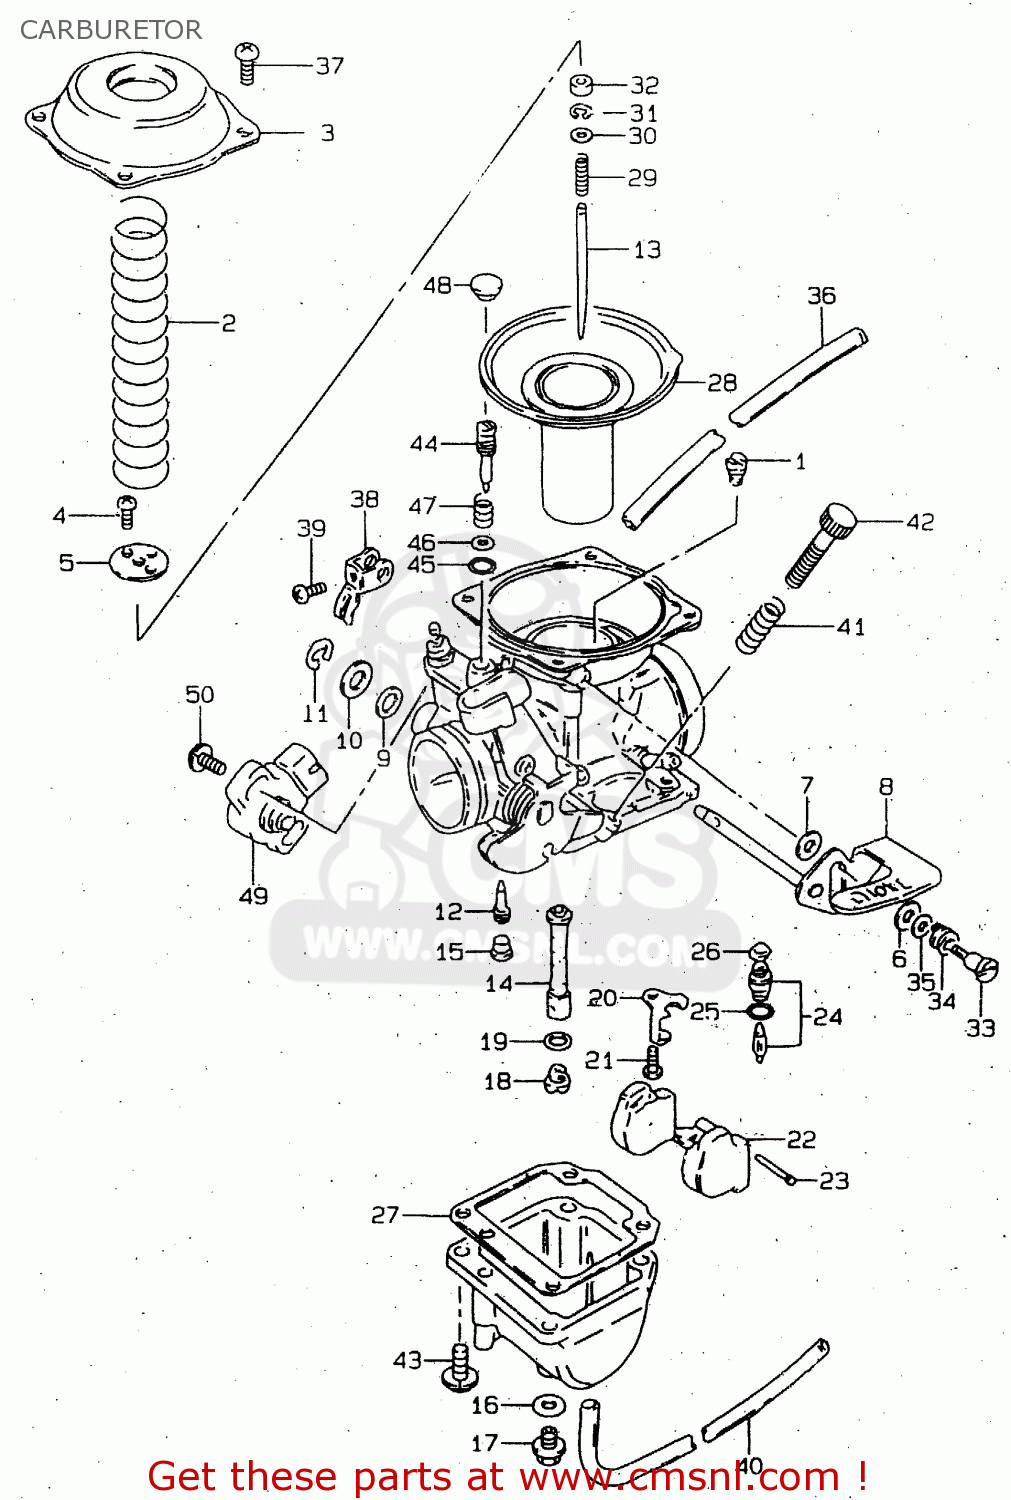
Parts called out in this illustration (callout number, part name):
1	JET,MAIN(180)
2	SPRING
3	COVER
4	SCREW
5	PLATE
6	PACKING (NAS)
7	WASHER(4.1X12X0.8)
8	SHAFT ASSY,STARTER
9	SEAL
10	GASKET,THROTTLE SHAFT (NAS)
11	E RING
12	JET,PILOT(35)
13	NEEDLE,JET
14	JET,NEEDLE(P-2)
15	PLUG,NEEDLE JET
16	GASKET (NAS)
17	PLUG,DRAIN
18	JET,MAIN(97.5)
19	WASHER
20	PLATE
21	SCREW 4X6
22	FLOAT
23	PIN,FLOAT
24	VALVE ASSY,NEEDLE
25	O-RING,NEEDLE VALVE
26	FILTER
27	GASKET,FLOAT CHAMBER (NAS)
28	DIAPHRAGM ASSY
29	SPRING
30	WASHER
31	CLIP
32	RING
33	SCREW
34	SPRING
35	WASHER,STARTER SHAFT
36	HOSE(5X8.2X600)
37	SCREW
38	LEVER
39	SCREW
40	HOSE(3.5X6.5X600)
41	SPRING,THROTTLE SCREW
42	ADJUSTER
43	SCREW
44	SCREW,PILOT
45	O RING,PILOT AIR SCREW
46	WASHER
47	SPRING
48	PLUG
49	SENSOR ASSY
50	SCREW, SENSOR
